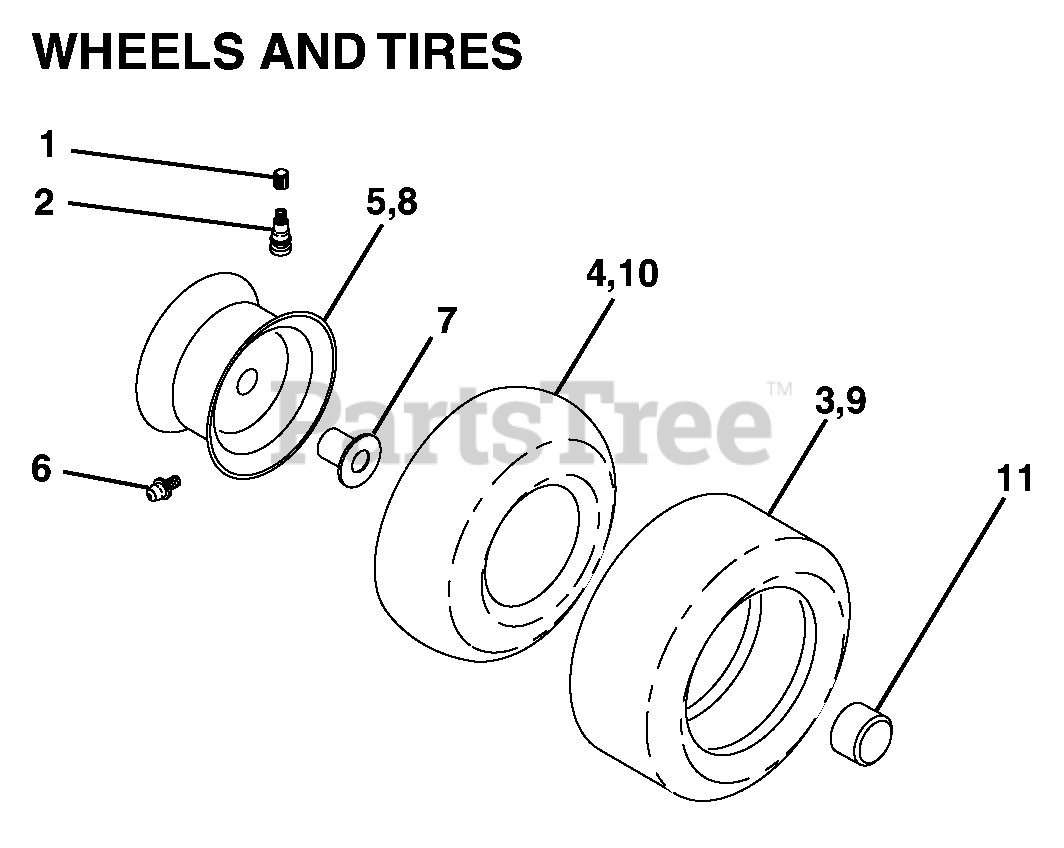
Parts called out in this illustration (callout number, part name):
1	Cap Valve Tire
2	Stem Valve
3	Tire F T 15 x 6 0 - 6 Service
4	Tube Front (Service Item Only)
5	Rim Asm 6" front Service
6	Fitting Grease (Front Wheel Only)
7	Bearing Flange (Front Wheel Only)
8	Rim Asm 8" rear Service
9	Tire R TS 20 x 8-8.C Service
10	Tube Rear (Service Item Only)
11	Cap Axle Blk 1 50 x 1 00
